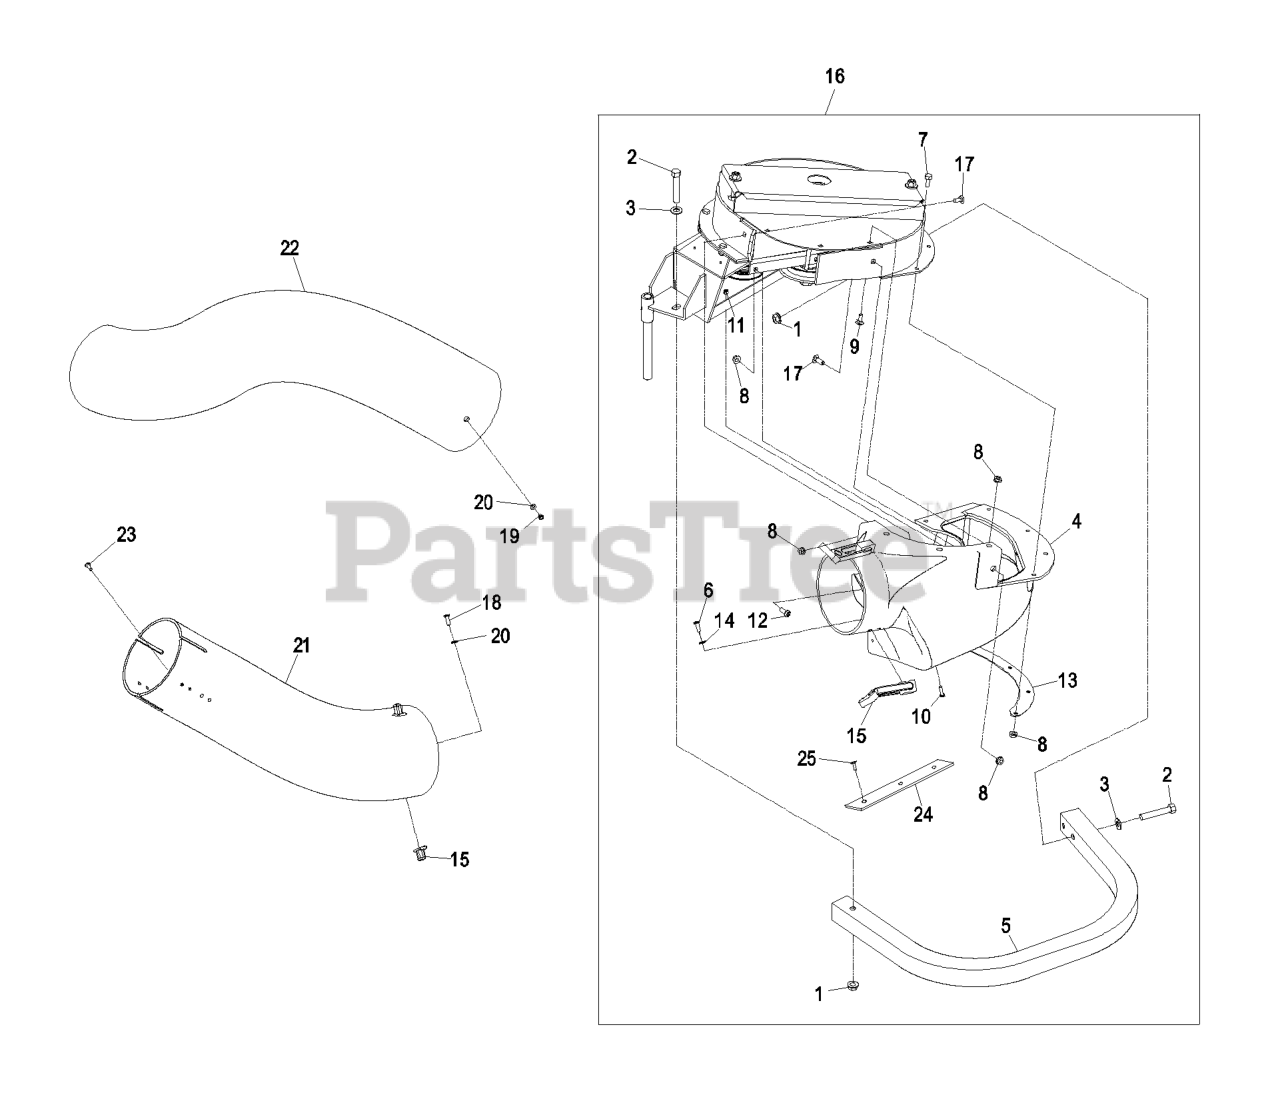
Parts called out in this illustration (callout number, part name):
1	NUT-HHF, WHIZ
2	SCREW-HH
3	WASHER-FLAT
4	ASM,BLOWER CHUTE SMALL
6	SCREW-PPH
7	SCREW-HH
9	SCREW-CARR
10	SCREW-HEAD, TRUSS
13	PLATE-BACKING, BLOWER
14	WASHER-FLAT
15	LATCH DRAW
16	ASM,BLOWER 44/48 - SERVIC
17	BOLT-CARR
18	SCREW-PPH
19	NUT-LOCK, NI
20	WASHER-FLAT
21	KIT,LOWER TUBE
22	TUBE,UPPER 44/48
23	SCREW-HWH
24	PLATE-REINFORCEMENT
25	RIVET-BLIND
